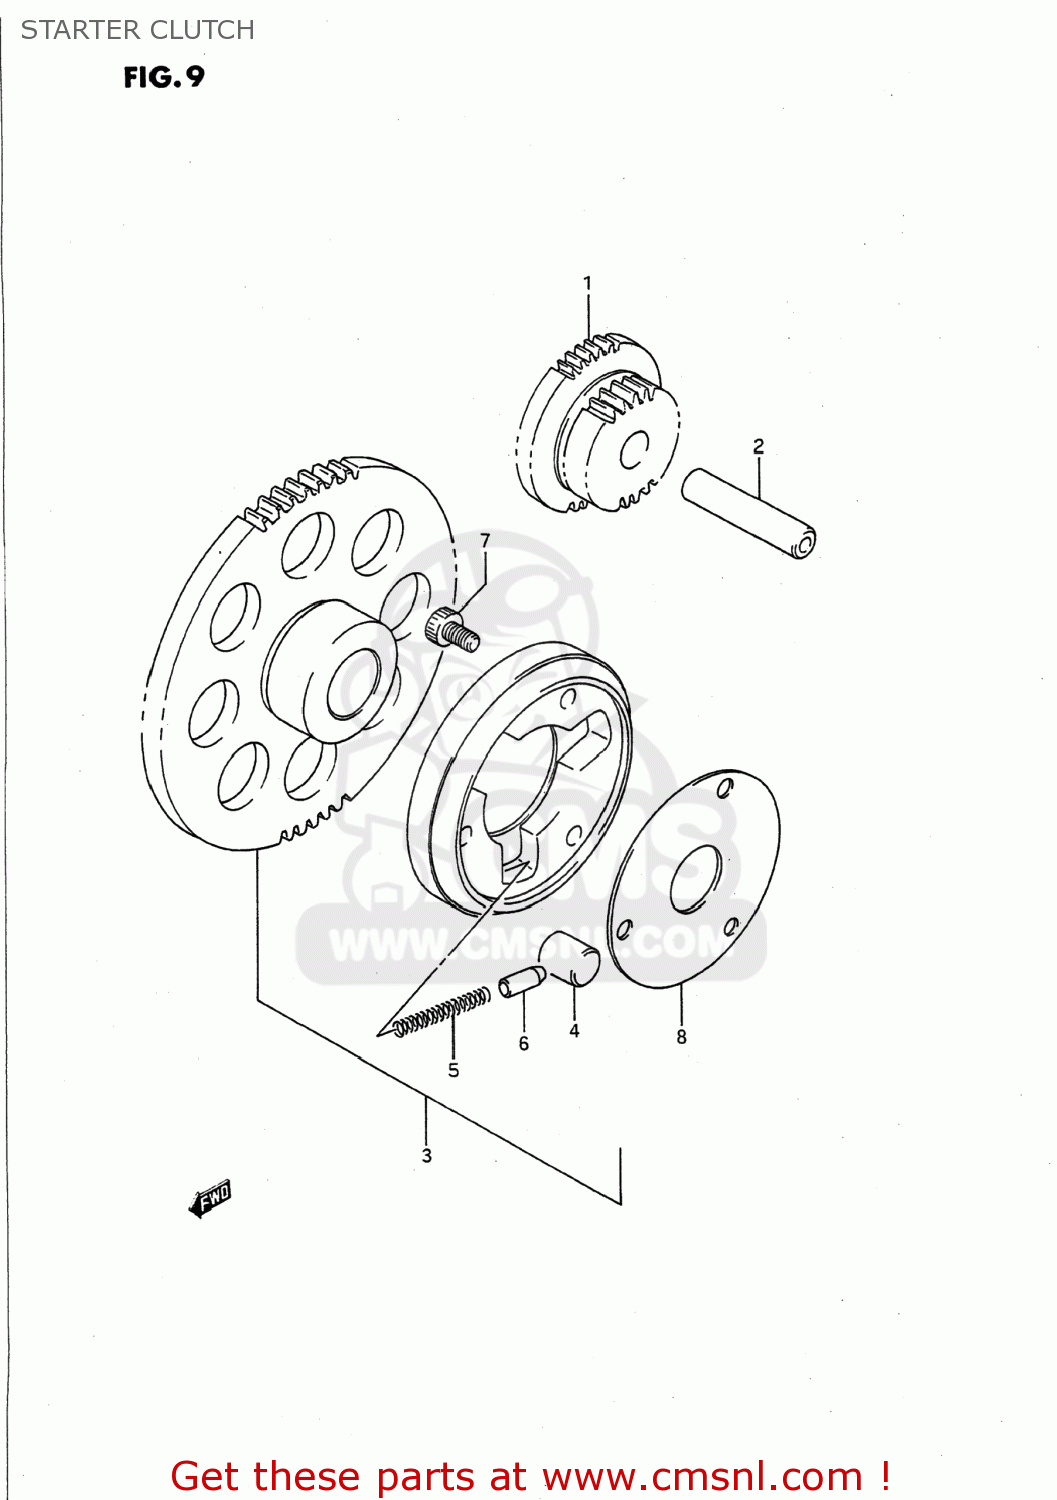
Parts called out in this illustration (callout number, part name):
1	GEAR,STARTER IDLE
2	PIN(7.4X13X56)
3	CLUTCH SET,STARTER
4	ROLLER(15X13)
5	SPRING
6	PIECE,PUSH
7	BOLT
8	SHIM,STARTER CLUTCH HUB
